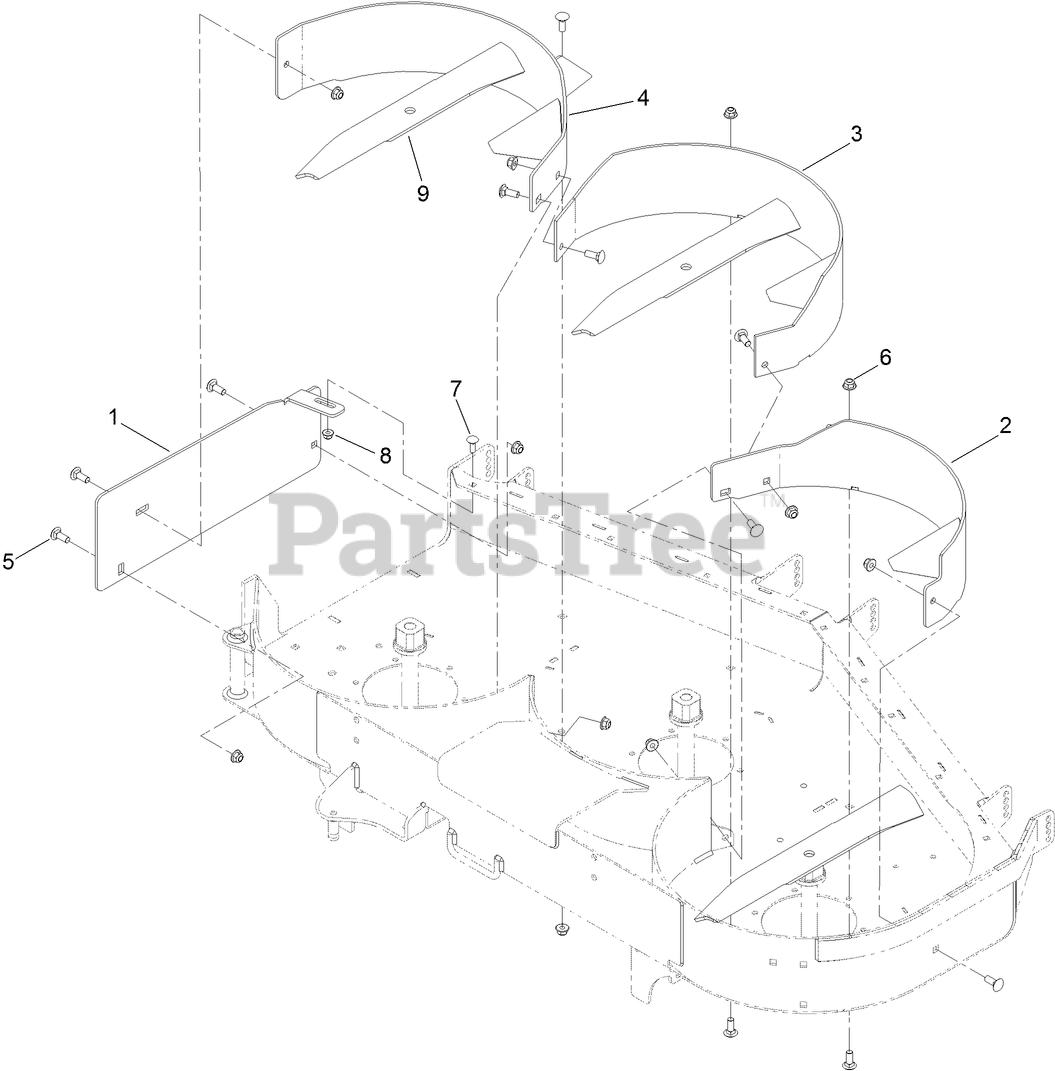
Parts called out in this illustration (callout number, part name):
1	PLATE-COVER, DISCHARGE
2	BAFFLE-LH
3	BAFFLE-CENTER
4	BAFFLE-RH
5	BOLT-CARR
6	NUT-HF, NI
7	SCREW-CARR
8	NUT-HF, NI
9	BLADE-ROTARY, RECYCLING 18.0IN
